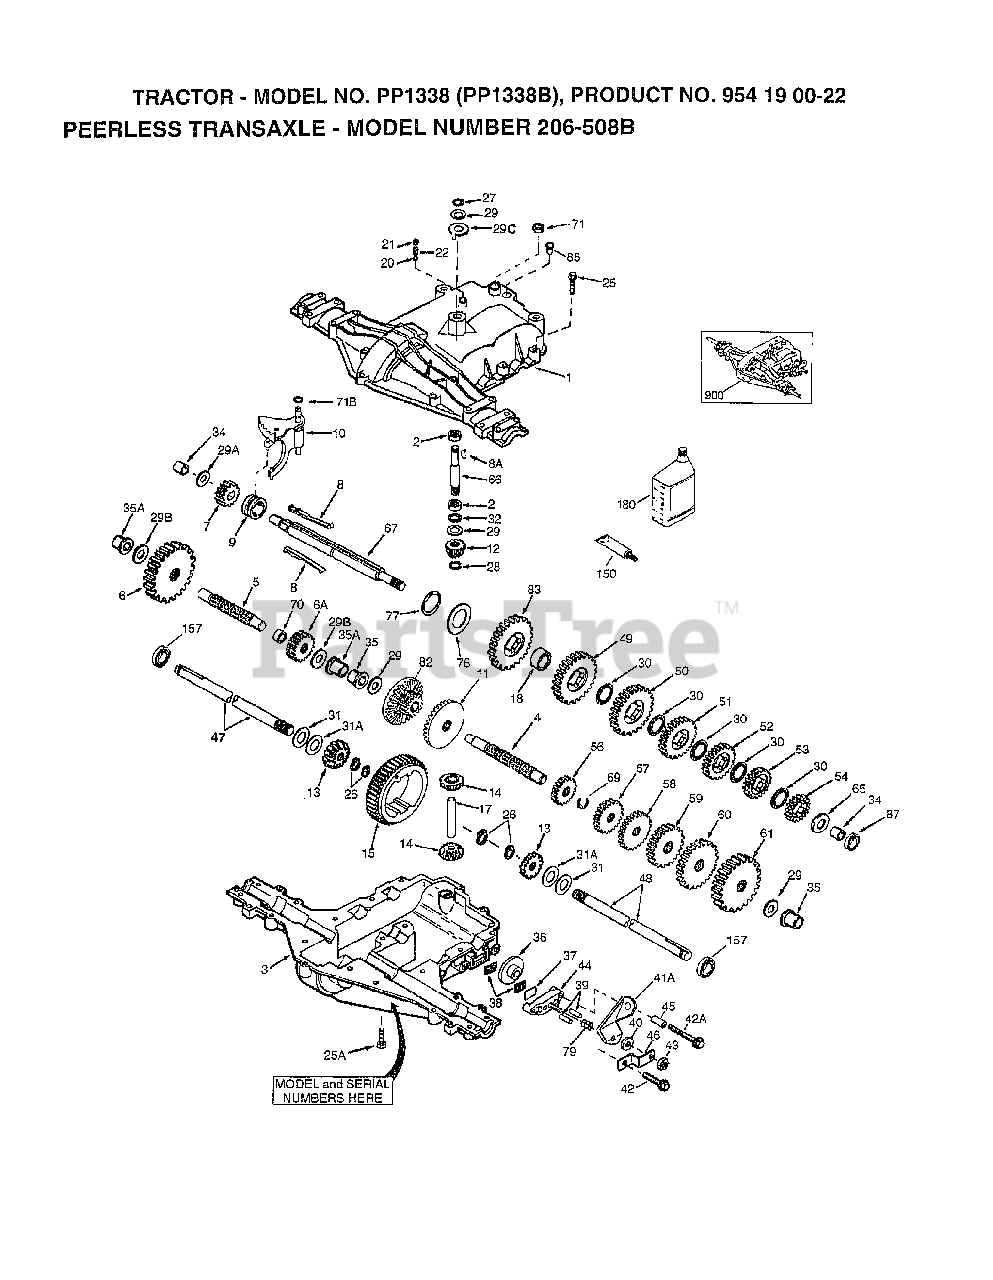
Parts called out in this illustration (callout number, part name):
1	TRANSAXLE COVER
2	NEEDLE BEARING 5/8" ID
3	TRANSAXLE CASE
4	COUNTERSHAFT
5	OUTPUT SHAFT
6	SPUR GEAR (38 TEETH)
6A	SPUR GEAR (15 TEETH)
7	SPUR GEAR (11 TEETH)
8A	KEY, WOODRUFF
9	COLLAR, SHIFTER
10	SHIFT ROD & FORK
11	BEVEL GEAR (30 TEETH)
12	INPUT BEVEL PINION (13TEETH)
13	BEVEL GEAR (13 TEETH)
14	BEVEL PINION (13 TEETH)
15	RING GEAR (43 TEETH)
18	SPACER, NEUTRAL
20	BALL STEEL, 5/16" DIA.
21	SCREW, 3/8-16 X 3/8"
25A	SCREW 1/4-20 X 1-3/8"
26	RING RETAINER
27	RING, RETAINER
28	RETAINING RING
29	WASHER THRUST
29B	WASHER THRUST
30	WASHER THRUST
31A	FLAT WASHER
32	OIL SEAL 5/8"
34	BUSHING 9/16"
35	FLANGED BUSHING 5/8" ID
35A	FLANGED BUSHING 3/4"
37	PLATE BRAKE PAD
41A	BRAKE LEVER
42A	SCREW, 1/4-20 X 2-1/4
43	LOCKNUT 5/16-24
44	HOLDER BRAKE PAD
46	BRKT BRAKE LEVER
49	SPUR GEAR (29 TEETH)
50	SPUR GEAR (27 TEETH)
51	SPUR GEAR (23 TEETH)
52	SPUR GEAR (19 TEETH)
53	SPUR GEAR (16 TEETH)
54	SPUR GEAR (15 TEETH)
56	SPUR GEAR (11 TEETH)
57	SPUR GEAR (13 TEETH)
58	SPUR GEAR (17 TEETH)
59	SPUR GEAR (21 TEETH)
60	SPUR GEAR (24 TEETH)
61	SPUR GEAR (25 TEETH)
66	INPUT SHAFT
67	SHIFTER & BRAKE SHAFT
69	RETAINING RING
70	SPACER .890
71	SEAL SQUARE CUT
76	WASHER, THRUST
77	INVERTED RETAINING RING
82	BEVEL & SPUR GEAR (30 & 13 TEETH)
83	SPUR GEAR (27 TEETH)
85	OIL FILL PLUG
87	OIL SEAL 9/16"
150	LIQUID GASKET RTV SILICONE
157	OIL SEAL 3/4"
180	GEAR OIL 80W90
